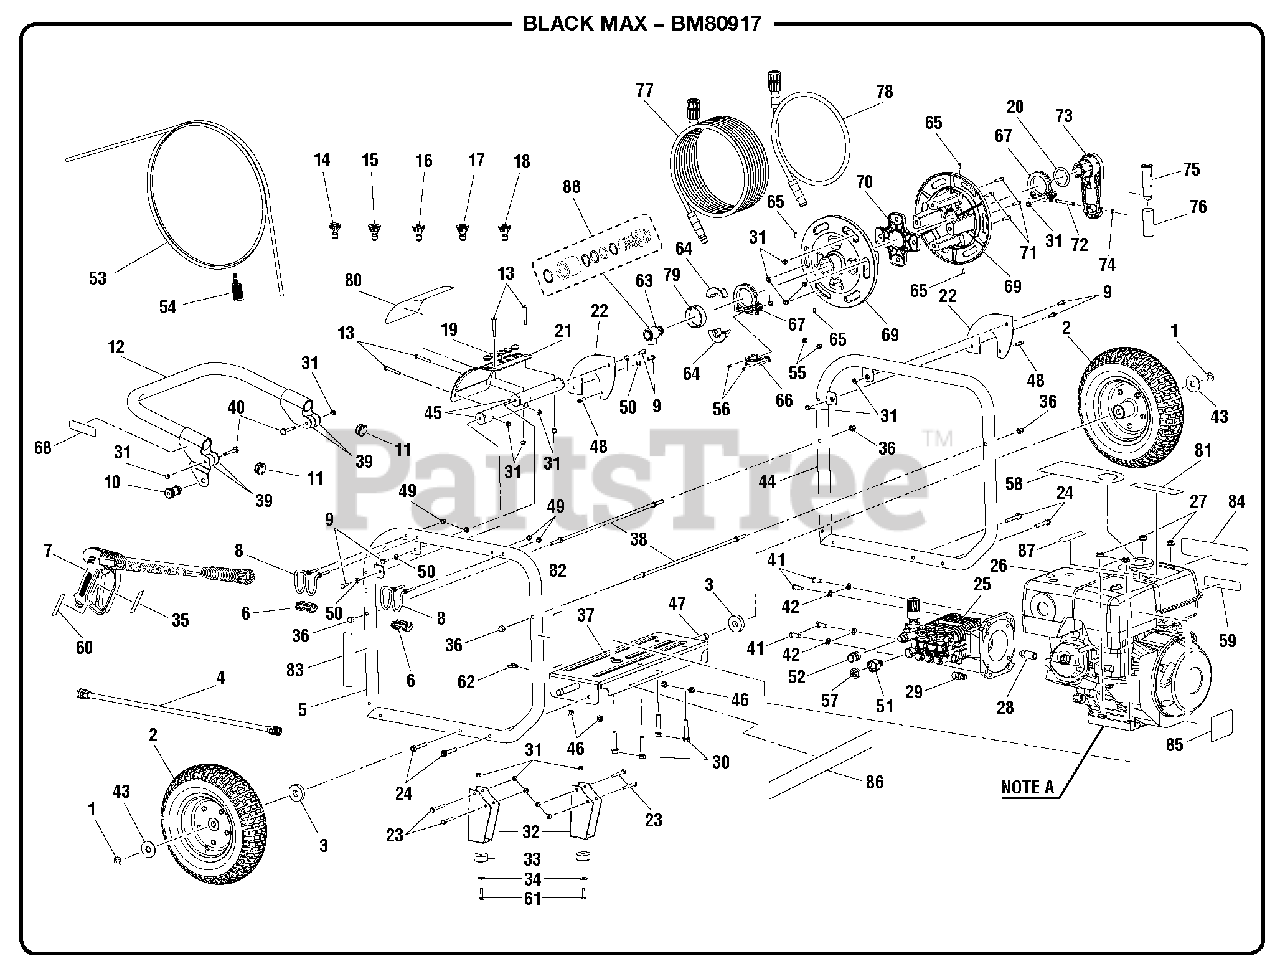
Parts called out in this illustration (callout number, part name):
1	Retaining Ring
2	Wheel Assembly (13 in. x 5 in.)
3	Axle Bushing
4	Spray Wand Assembly
5	Main Frame (Right)
6	Rubber Piece
7	Trigger Handle Assembly
8	Wand Holder
9	Bolt (1/4-20 x 19 mm Hex Hd.)
10	Handle Release Knob
11	Handle Tube Cap
12	Handle Assembly
13	Screw (1/4-20 x 2 in. T30 Torx Truss Hd.)
14	Soap Nozzle (Black)
15	40deg Nozzle (White)
16	25deg Nozzle (Green)
17	15deg Nozzle (Yellow)
18	0deg Nozzle (Red)
19	Nozzle Grommet
20	Reel Gasket
21	Nozzle Holder Panel Assembly (Inc. Key No. 19)
22	Reel Support Bracket
23	Bolt (1/4-20 x 53 mm Hex Hd.)
24	Bolt (M8 x 50 mm Flange Hex Hd.)
27	Lock Nut (M10)
28	Pressure Relief Valve
29	Thermal Relief Valve
30	Bolt (M10 x 50 mm Hex Hd.)
31	Lock Nut (1/4-20)
32	Bracket
33	Rubber Wear Pad
34	Washer (1/4 in.)
35	Trigger Handle Warning Label (Fr./Sp.)
36	Cap Nut (M8 x 1-1/4 in.)
37	Engine Plate
39	Washer (D34 x d9 x 1.8t)
40	Connector Pin (1/4 in.)
41	Bolt (3/8 in. x 25 mm)
42	Lock Washer (3/8 in.)
43	Washer (5/8 in.)
44	Main Frame (Left)
45	Frame Panel Support
46	Lock Nut (M8)
48	Bolt (1/4-20 x 12.5 mm Hex Soc. Hd.)
49	Lock Nut (M6)
50	Lock Washer (1/4 in.)
51	Adaptor (1/2 M to 3/4 F)
52	Adaptor (3/8 F to M22 M)
53	Chemical Siphon Tube
54	Chemical Siphon Filter
55	Hex Nut (M4)
56	Screw (M4 x 22 mm)
57	Filter Screen
59	Oil Warning Label
60	Trigger Handle Warning Label
61	Bolt (1/4-20 x 1 in. Hex Hd.)
62	Chemical Siphon Hose Holder
63	Pivot Fitting (Inc. Key No. 88)
64	Pivot Fitting Holder
65	Screw (4-18 x 10 mm)
66	Reel Fitting Saddle
67	Reel Bearing
68	Handle Release Label
69	Reel Half
70	Reel Center Support
71	Bolt (1/4-20 x 1 in. Hex Soc. Hd.)
72	Reel Handle Pin
73	Reel Handle (Right)
74	Retaining Clip
75	Reel Handle (Left)
77	Hose (50 ft.)
78	Hose (Pump to Reel)
79	Handle Sleeve
80	Large Performance Label
81	Hot Surface Label
82	Engine Quick Start Label
83	Pump Quick Start Label
84	Danger Label
85	Small Performance Label
86	Data Plate
87	Customer Service Label
